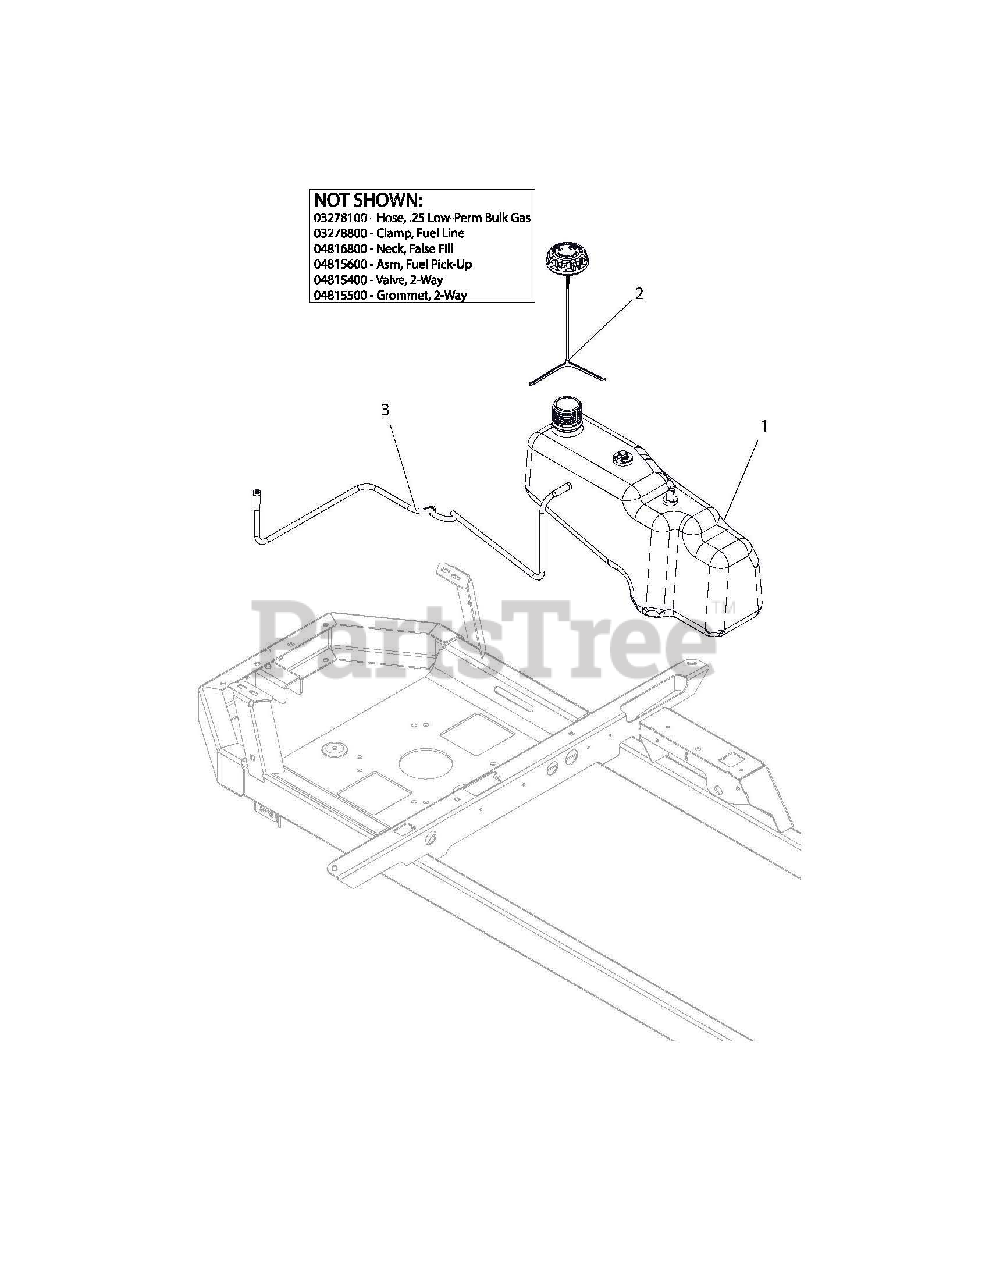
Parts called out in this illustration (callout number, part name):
1	ASM,TANK NON-PERM FUEL
2	CAP, FUEL VENT-IN 2.25" RATCH.
3	LINE, FUEL VENT KOHLER
